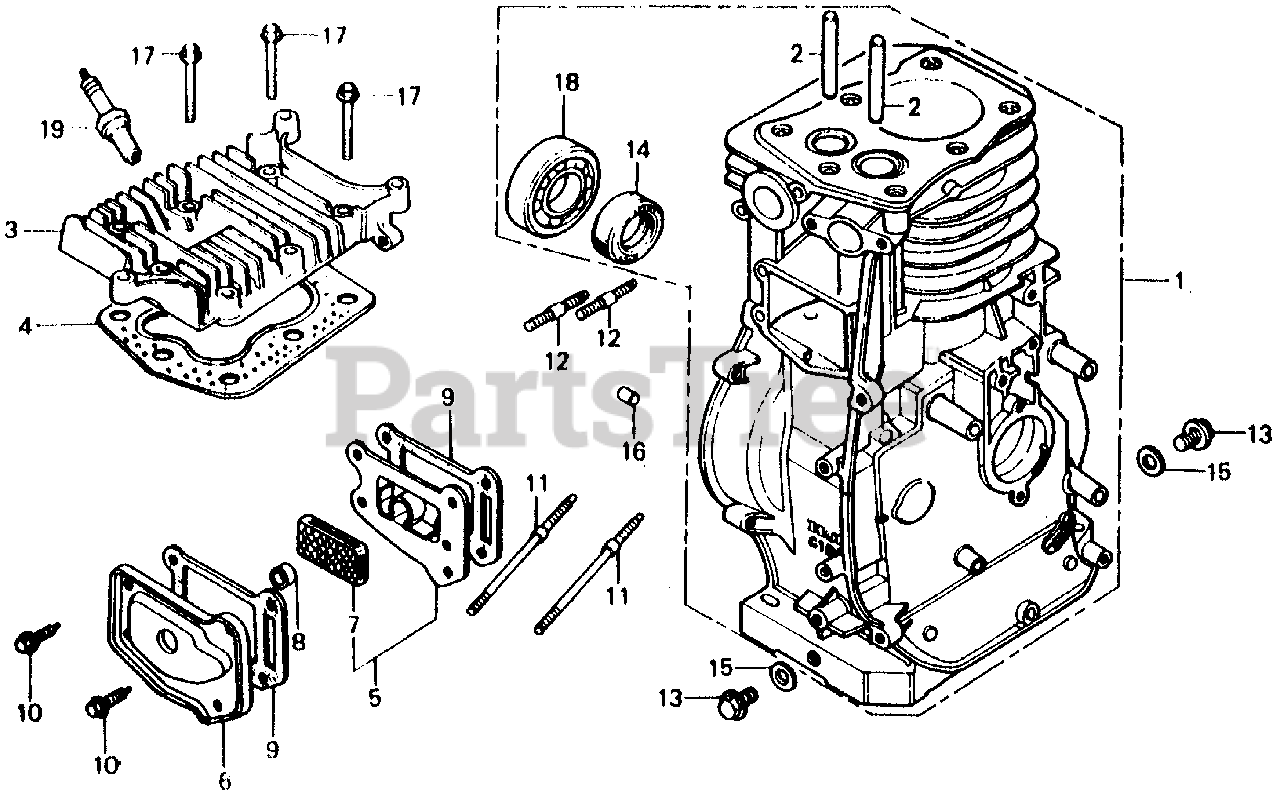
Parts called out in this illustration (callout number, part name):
1	CYLINDER ASSY.
2	GUIDE, VALVE (OS)
3	CYLINDER HEAD
4	GASKET, CYLINDER HEAD
5	CASE, BREATHER
6	COVER, TAPPET ROOM
7	FILTER, BREATHER
8	SEAL, BREATHER
9	GASKET, TAPPET COVER
10	BOLT, FLANGE (6X12) (CT200)
11	BOLT, STUD (6X89)
12	BOLT, STUD (8X35)
13	BOLT, DRAIN PLUG
14	OIL SEAL (25X41X6)
15	WASHER, DRAIN PLUG (12MM)
16	PIN A, DOWEL (8X14)
17	BOLT, FLANGE (8X45)
18	BEARING, RADIAL BALL (6205)
19	SPARK PLUG (BR-4HS) (NGK)
19	SPARK PLUG (W14FR-U) (DENSO)
